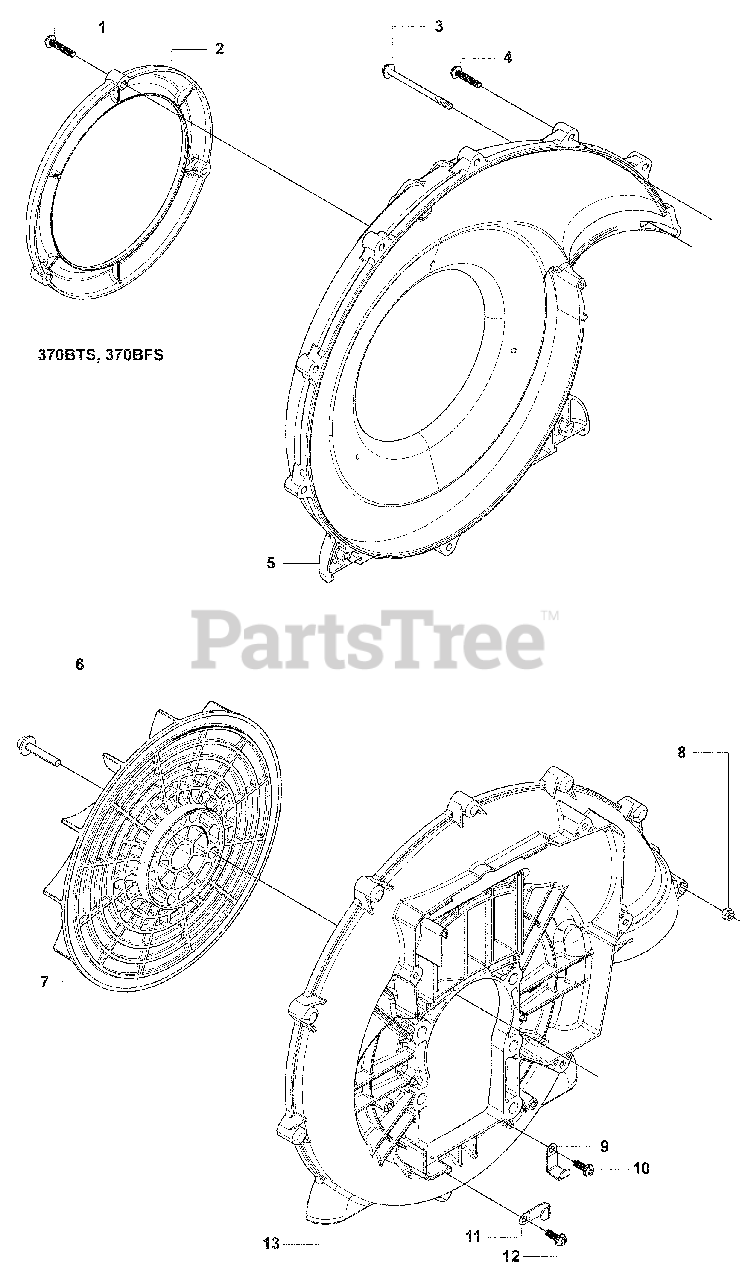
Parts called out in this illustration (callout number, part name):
1	Screw
2	FUNNEL
4	Screw
5	Volute Cover
6	Bolt
8	Nut
9	CLAMP (BT Only)
10	Screw
11	Clamp
12	Screw
13	Volute Case
